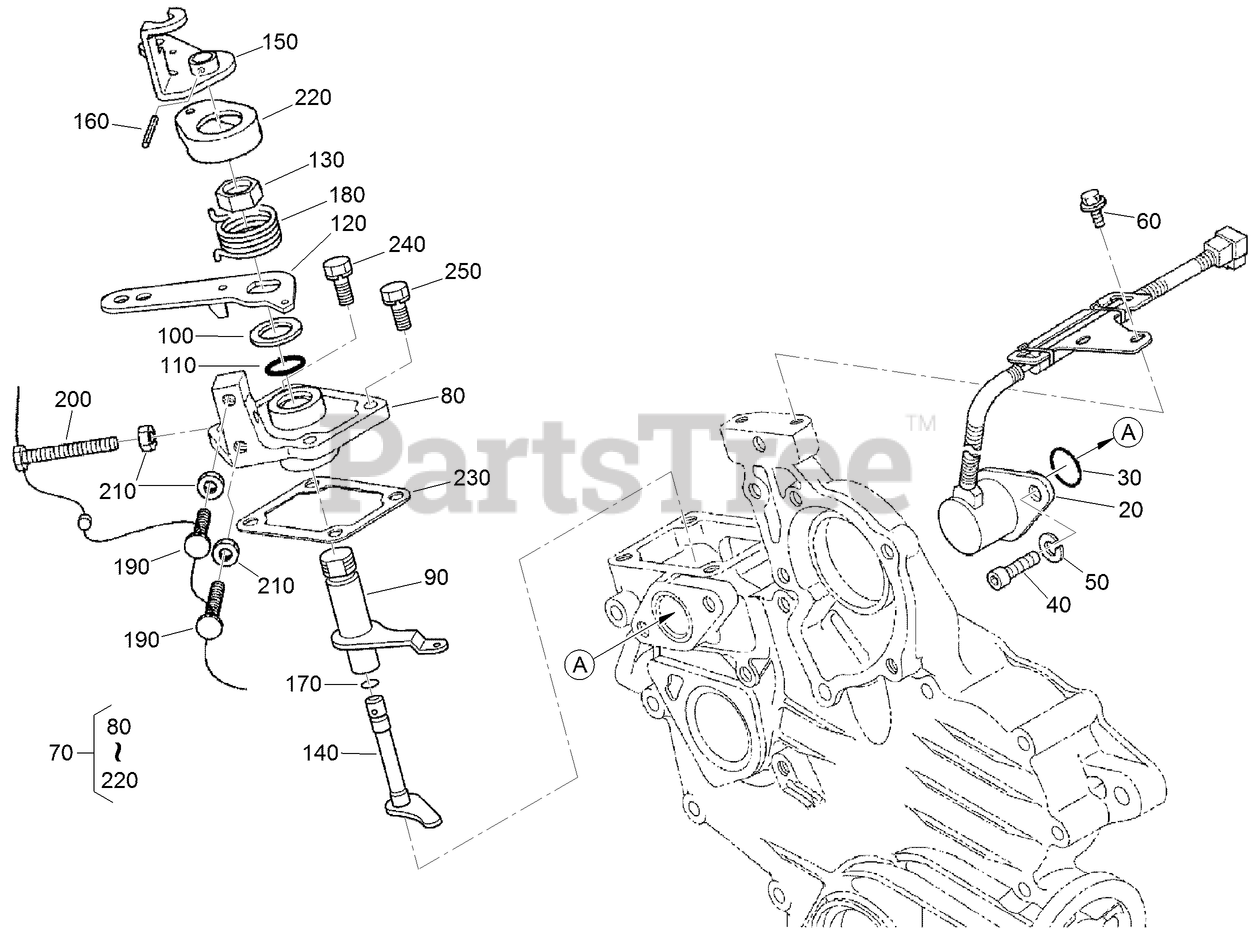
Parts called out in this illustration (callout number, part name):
20	SOLENOID STOP ASM
30	O-RING
40	BOLT-HSH
50	WASHER-SPRING
60	BOLT-FLANGE
70	SPEED CONTROL PLATE ASM
80	PLATE-CONTROL, SPEED
90	LEVER-GOVERNOR
100	COLLAR
110	O-RING
120	LEVER-CONTROL, SPEED
130	NUT-CONTROL, SPEED
140	SHAFT-LEVER
150	LEVER-STOP, ENGINE
160	PIN-SPRING
170	O-RING
180	SPRING-RETURN
190	SCREW-STOPPER
230	GASKET-PLATE, CONTROL
240	BOLT-FLANGE
